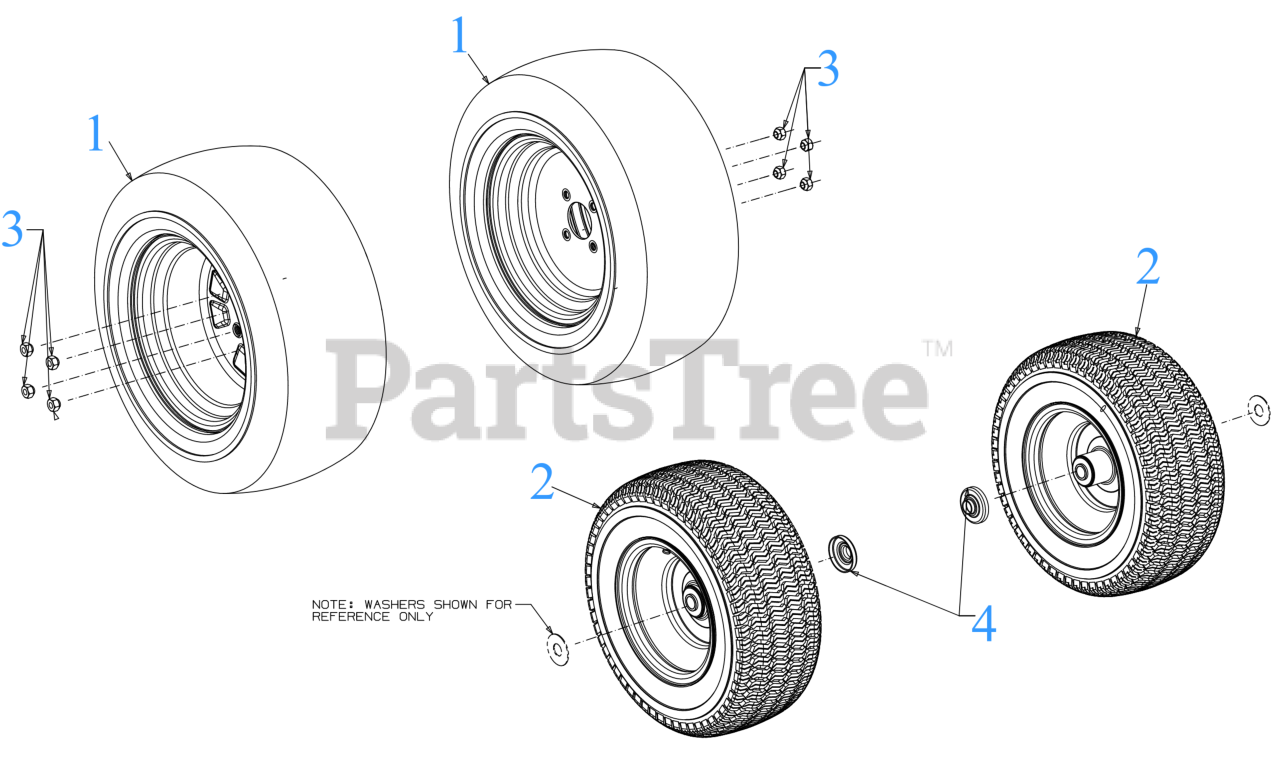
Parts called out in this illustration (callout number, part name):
1	TUBELESS AIR VALVE
1	REPLACEMENT RIM (12X7)
2	TIRE 16X6.5X8 CARLISLE
2	LUBE FITTING
3	LUG NUT 7/16-14
4	WHEEL BEARING COVER
